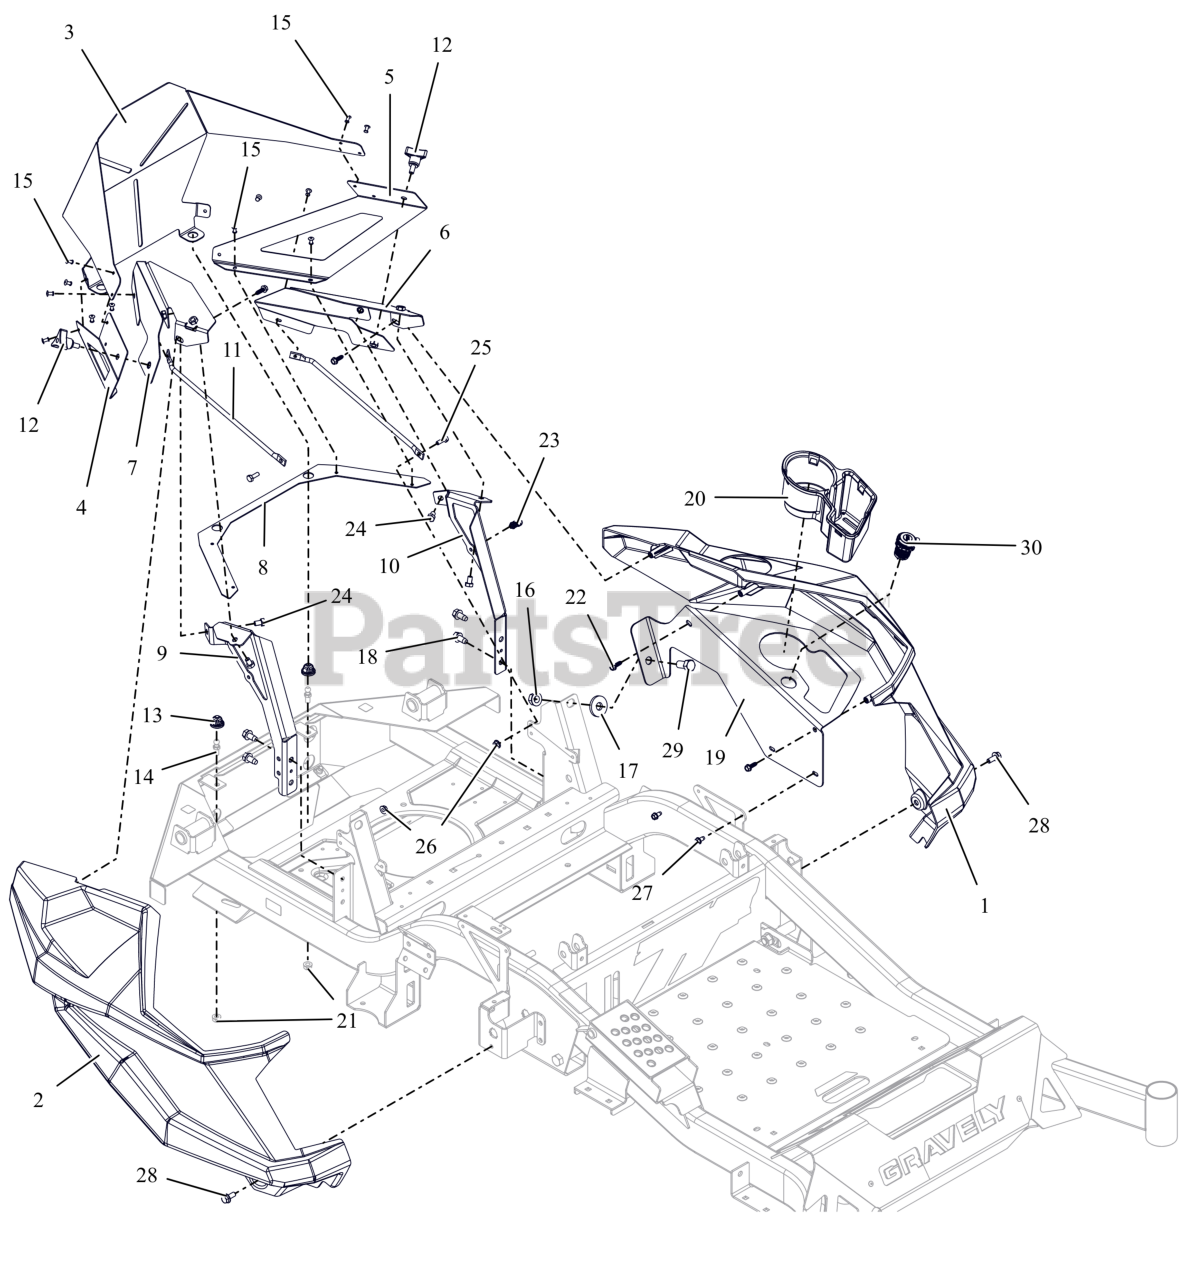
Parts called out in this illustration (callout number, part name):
1	FENDER, LH
2	FENDER, RH
3	WRAP, REAR (BLACK)
4	WRAP- REAR - RH
5	WRAP- REAR - LH
6	PANEL- LH
7	PANEL- RH
8	STIFFNER- BACKWRAP
9	BRKT- RH FENDER MTG
10	BRKT, LH FENDER MTG (MATTE BLACK)
11	ROD, STIFFENER
12	KNOB,WING STUD 5/16-18 X .75
13	GROMMET, 10MM BOLLHOFF
14	STUD- BALL
15	RIVET, #66 STEEL POP PD BLACK
16	NUT-LK-TOP-FLG .500-13 GF ZCC
17	WASHER- FLT .562X1.50X.187 ZCC
18	SCR,TAP .375-16X.75 HWH TR ZCC
19	PANEL, HD CUPHOLDER (MATTE BLACK)
20	HOLDER, CUP
21	NUT,LK-CTR-FLG .31-18 GF ZCC
22	SCR, PLASTITE-HWH 0.25 X 0.75 ZC120
23	CLIP, CABLE GUIDE
24	BLT, HEX .31-18X.50 GR5 ZCC
25	BLT, HEX .25-20X.75 G5 ZCC
26	NUT-LK-CTR-FLG .25-20 ZC120
27	SCR-TAP .25-20X.50 HWH ZCC
28	BLT, SERHFWH 0.312-18X0.75 GR5 ZCC
29	BLT, HEX .50-13X1.00 G5 ZCC
30	USB, DUAL PORT USB-C, 12V BLK
